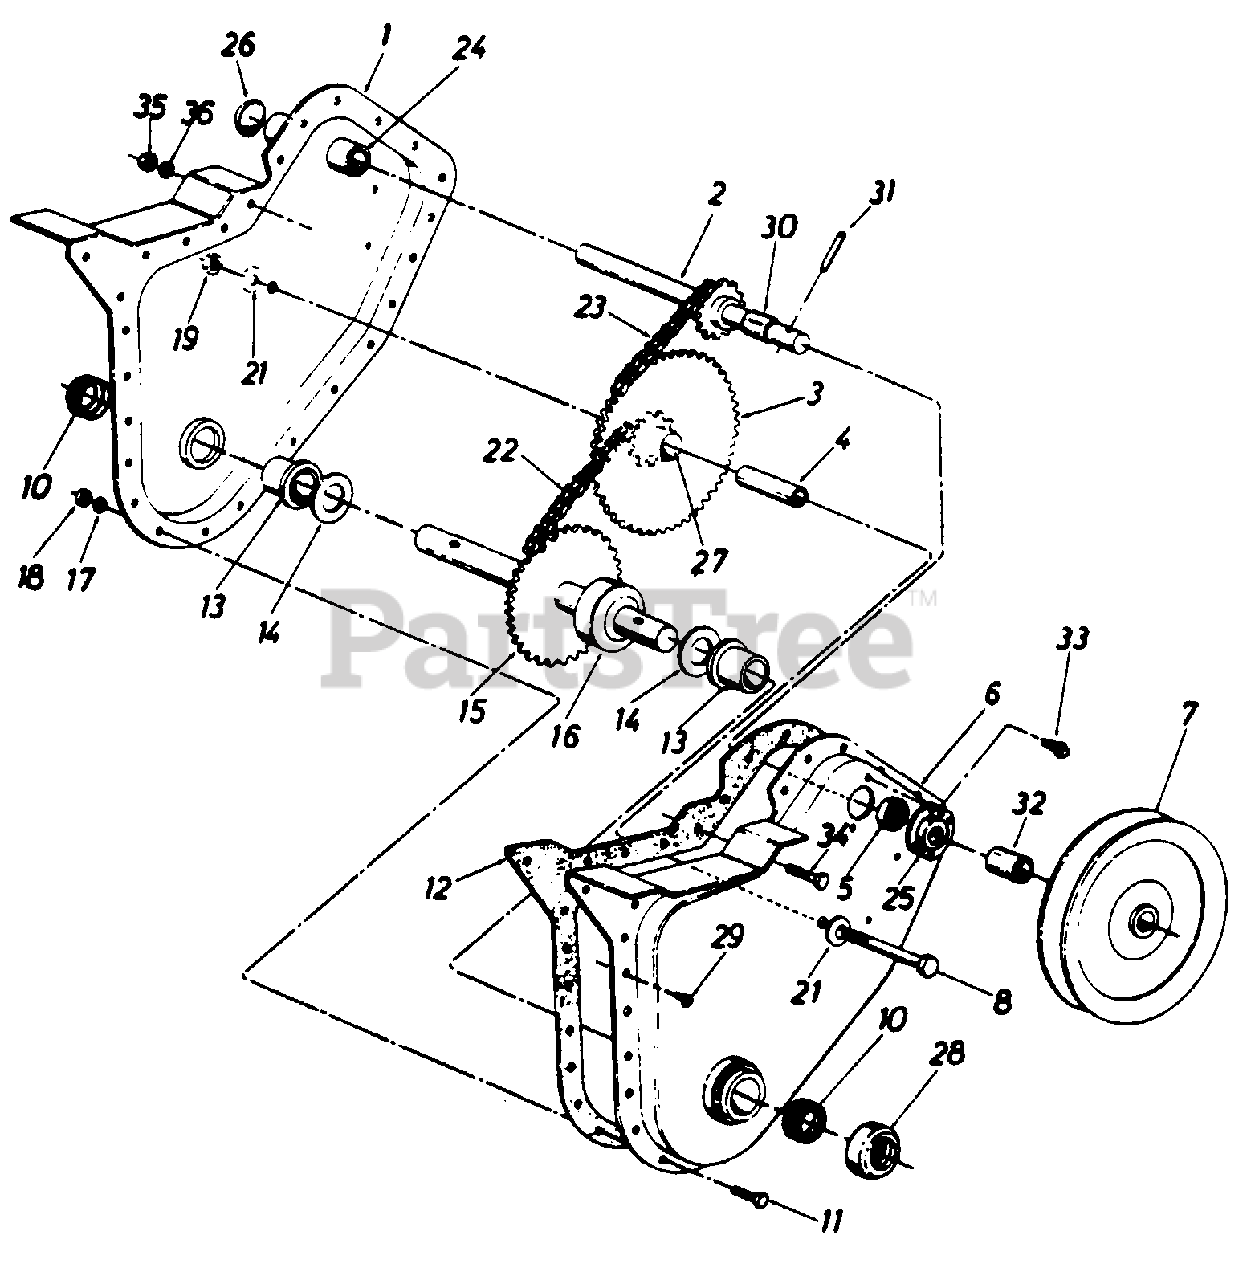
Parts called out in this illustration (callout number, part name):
1	RH Chain Case Ass'y
2	Input Shatt Assembly
3	Hub & Sprocket Assembly
4	Bearing Inner Race
5	Ball Bearing
6	LH Chain Case Ass'y
7	Pulley - Chain Case
8	Hex Bolt 3/8-24 x 2-1/2
11	Hex Bolt 1/4-28 x 5/8
12	Gasket
13	Flange Bearing 879 I D
14	Flat Washer
15	Tine Shaft Assembly
16	Spacer
17	Lock Washer 1/4 Spring
18	Hex Nut 1/4-28
19	Hex Lock Nut 3/8-24
21	Bell Washer 3/8
22	Chain #420 1/2 Pitch 38 Links
23	Chain #35 3/8 Pitch 50 Links
24	Bearing
25	Bearing Housing
26	Expansion Plug
27	Bearing
28	Dust Cap
29	Hex Tap. Screw 1/4-20 x 1/2
30	Spacer
31	Sprol Spring Pin 1/4 x 1-1/2
32	Spacer
33	Hex Tap. Screw 1/4-20 x 3/8
34	Hex Bolt 5/16-18 x 3/4
35	Hex Nut 5/16-18
36	Lock Washer 5/16 Spring
